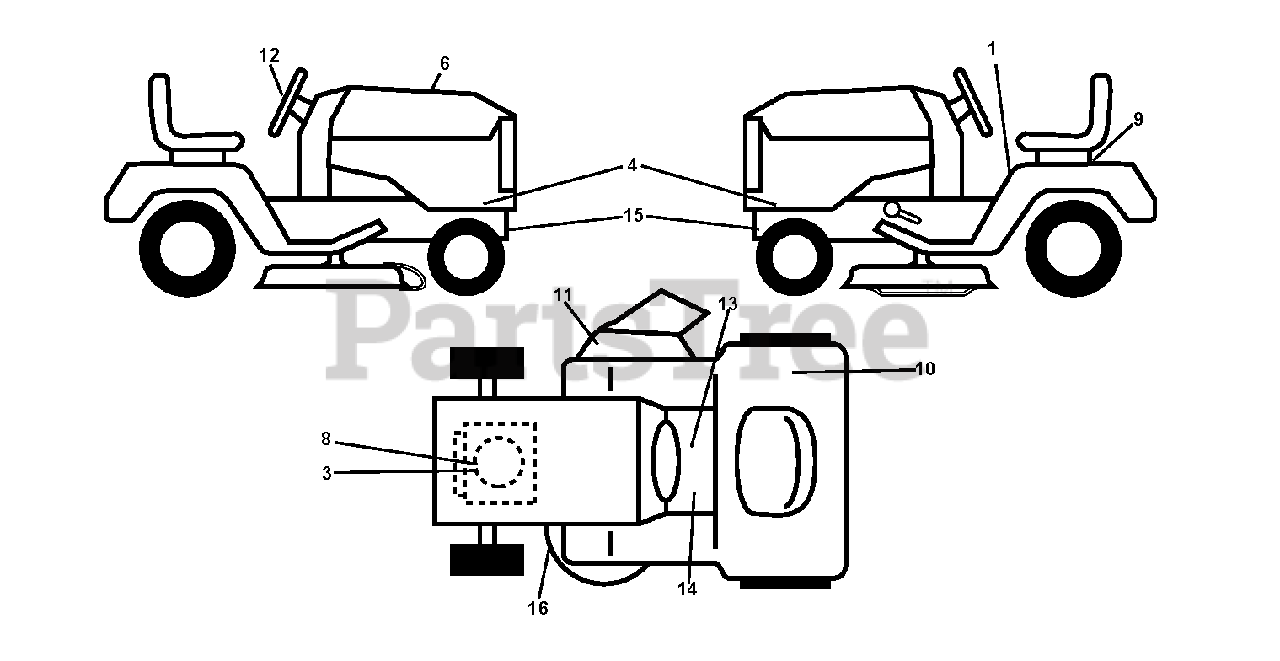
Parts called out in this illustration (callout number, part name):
9	DECAL BTRY SYMBOLS
11	DECAL, WARN. DEFLECT/CTFGR
13	DECAL PARK BRAKE
